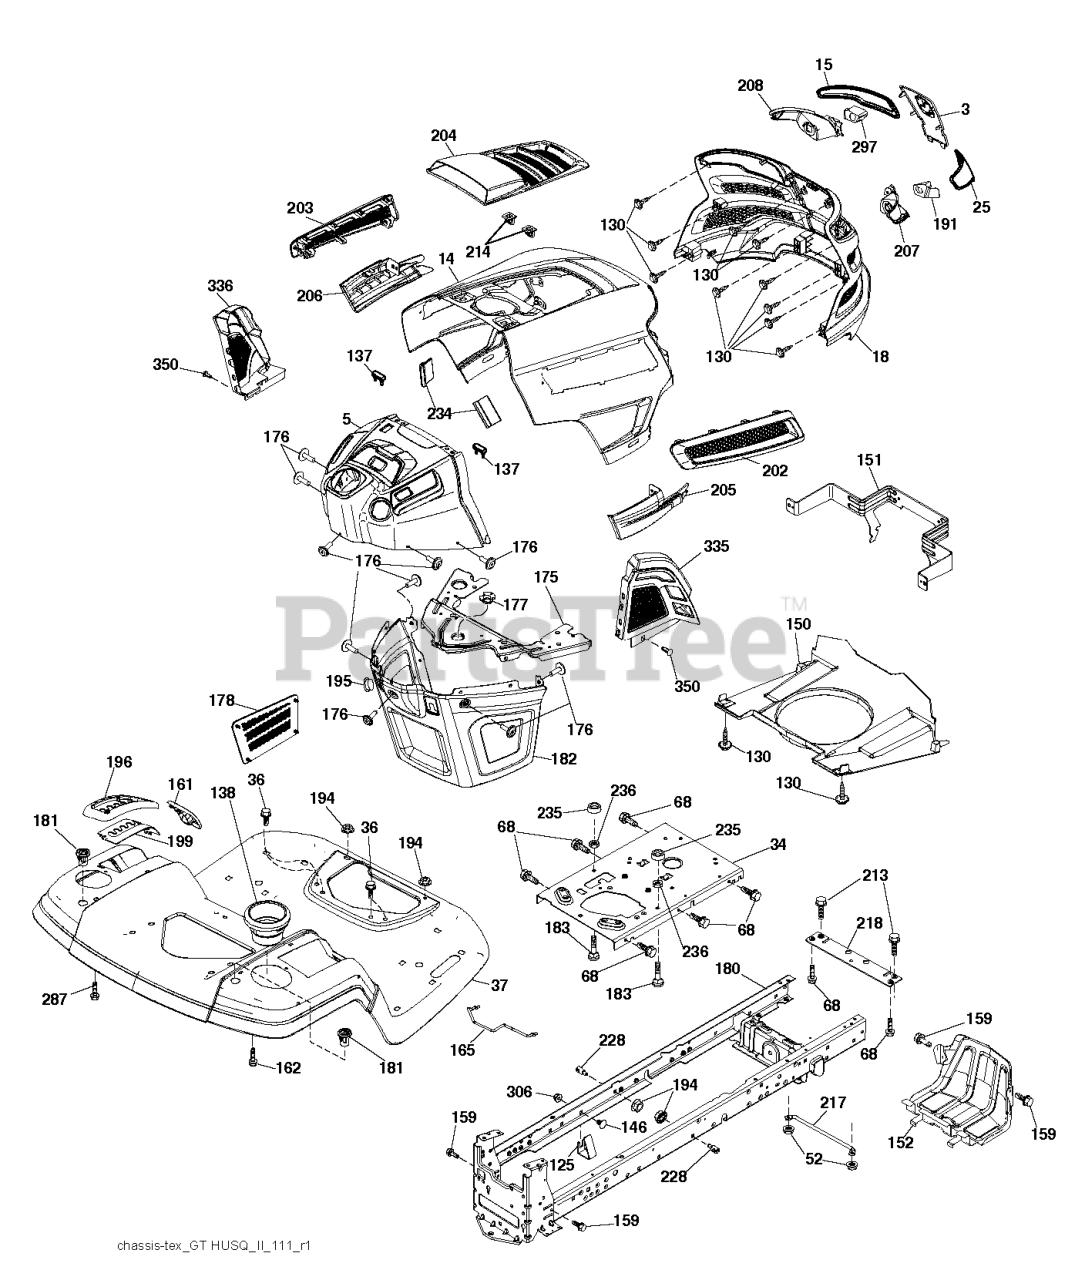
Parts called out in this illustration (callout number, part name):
3	APPLIQUE.SUBASM.GT.HUSQ.II
5	DASH.UPPER.ASSY.GT2.GREY
14	HOOD.ASM.DIXON.GT.TEX.BLUE
15	LENS.HEADLIGHT.LH.GTII.2011
18	GRILLE.SUBSTRATE.2011.
25	LENS.HEADLIGHT.RH.GTII.2011
34	PLATE.ENGINE.WELDED.CHASSIS
36	SCREW 5/16"
37	FENDER.ERGO.LT.W/CPH.W/FW.ORNG
52	LOCKNUT
68	SCREW LT
130	SCREW.#10 X 0.750.BOS
137	BUMPER DASH
138	HOLDER.CUP.LT.GREY
150	AIR.DUCT.GTV.BLACK
151	BRACKET.PIVOT.HOOD.GT.HUSQ.II
152	SHIELD.BROWNING.PNT.GT.V2
159	SCREW, 3/8-16X3/4
161	WINDOW.FUEL.LT.HUSQ.TEX.498
162	SCREW.HI-LO.CONSOLE
165	SUPPORT.TANK.REAR.W/TEX
175	PLATE.CROSSMEMBER.HUSQ
176	SCREW.#10-24X5/8.RN.QU
177	BUSHING, STEERING
178	CARGO.ASM.NET.TXGT.W/C
180	CHASSIS
181	BUSHING.MNT.FEND.CRGO.TEX.49
182	DASH.LOWER.COMMON.12V.ADAPTOR
183	BOLT.5/16-18X1-1/4 FULL THD
191	INSERT.REFLECTIVE.RH.HUSQ.GTII
194	NUT LOCK HEX FLANGE 5/16-18
195	PLUG.HOLE.DASH.LOWER.12V.BLK
196	DECKLFT.CONSOL FULL ASSM GREY
199	PLATE.DECK.LIFT.HUSQ.LT
202	VENT.SIDE.RH.GT.HUSQ.II.
203	VENT.SIDE.LH.GT.HUSQ.II.498
204	VENT.TOP.HUSQ.GT2
205	SIDE.TRIM.RH.GT.HUSQ.II
206	SIDE.TRIM.LH.GT.HUSQ.II.GRAY
207	BEZEL LIGHT.RH.GT.II.MYLAR
208	BEZEL LIGHT.LH.GT.II.MYLAR
213	BOLT
214	CLIP.RETAINER.TINNER.
217	ROD.PIVOT.HOOD
218	X-PIECE.HOOD.STOP.NON/
228	STUD.FASTNER.W/ANTI-ROTATE
234	BUMPER.HOOD.TEX.HUSQVARNA
235	SPACER FENDER
236	NUT.CENTERLOCK.5/16-
287	SCREW 1/4X20
297	INSERT.REFLECTIVE.LH.HUSQ.GTII
335	COVER.LOWER.DASH.RH.BLACK
336	COVER-LH.LOWER.DASH.GT2.BLACK
350	CLIP.X-MAS.TREE
